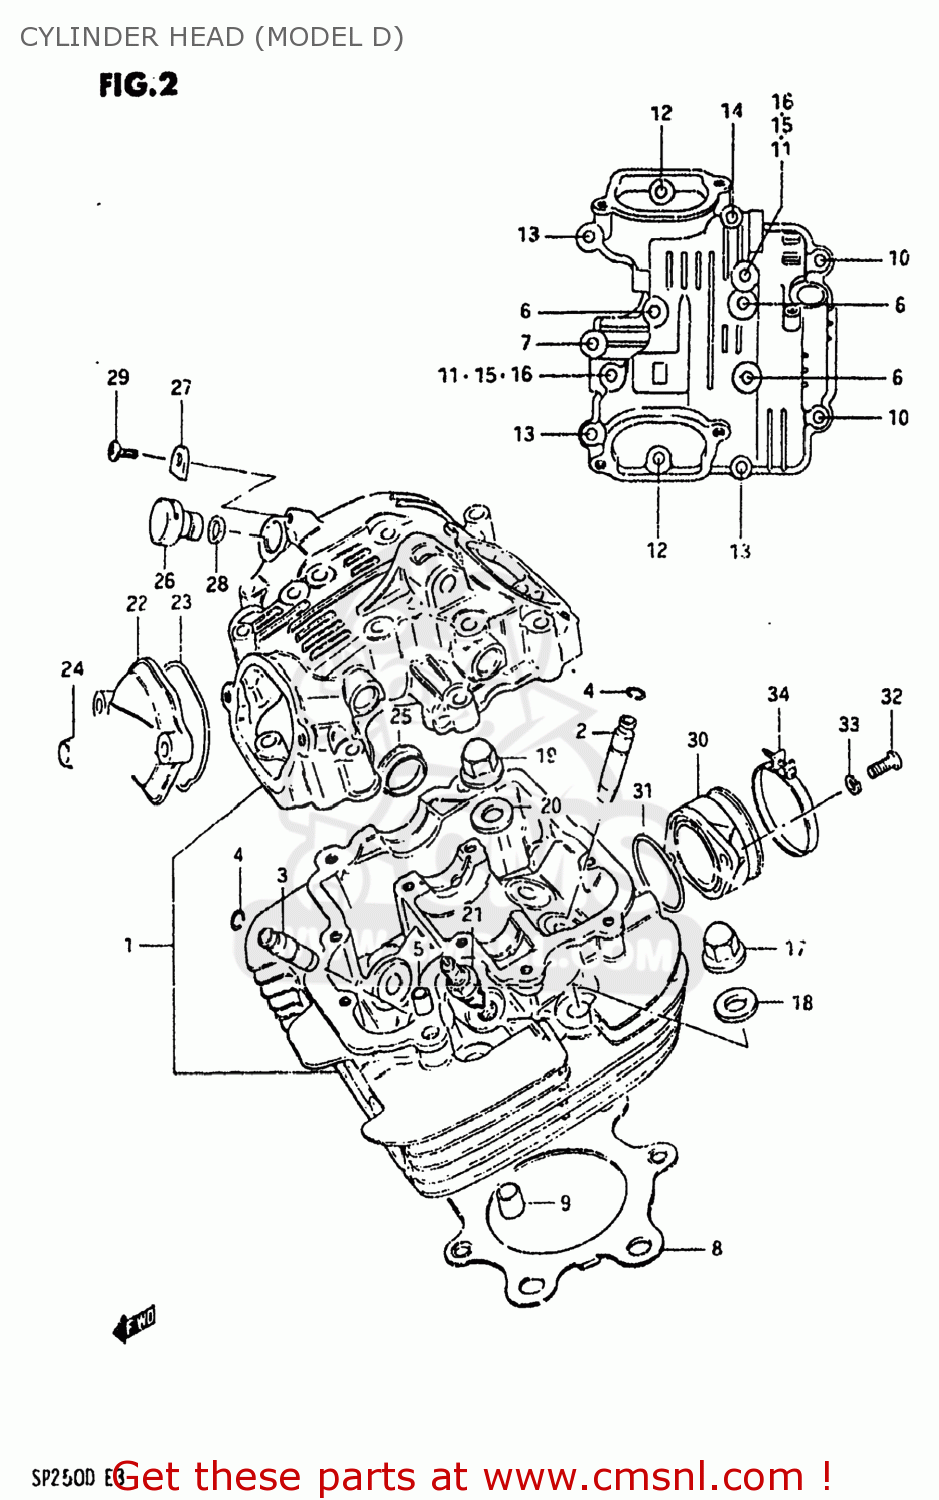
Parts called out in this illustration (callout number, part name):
1	HEAD ASSEMBLY,CYLINDER
2	GUIDE,INTAKE VALVE
3	GUIDE,VALVE
4	RING,SNAP
5	PIN(6.2X8X11)
6	BOLT ,6X60
7	BOLT 6X30
8	GASKET,CYLINDER HEAD (NAS)
9	PIN
10	BOLT
11	BOLT (6X30)
12	BOLT 6X30
13	BOLT (6X45)
14	BOLT ,6X60
15	NUT
16	GASKET (NAS)
17	NUT
18	WASHER (10.5X22X2.3)
19	NUT
20	GASKET(10.5X22X2) (NAS)
21	SPARK PLUG D8EA
22	CAP,INSPECTION
23	O RING(D:2.4,ID:23)
24	BOLT
25	PLUG(OD:30)
26	PLUG,TACH GEAR SLEEVE HOLE
27	PLATE,TACH DRIVE GEAR SLEEVE
28	SEAL,TACHOMETER DRIVEN
29	SCREW(5X12)
30	PIPE,INTAKE
31	O-RING (D:2.4 ID:39.7)
32	SCREW
33	LOCK WASHER
34	CLAMP
